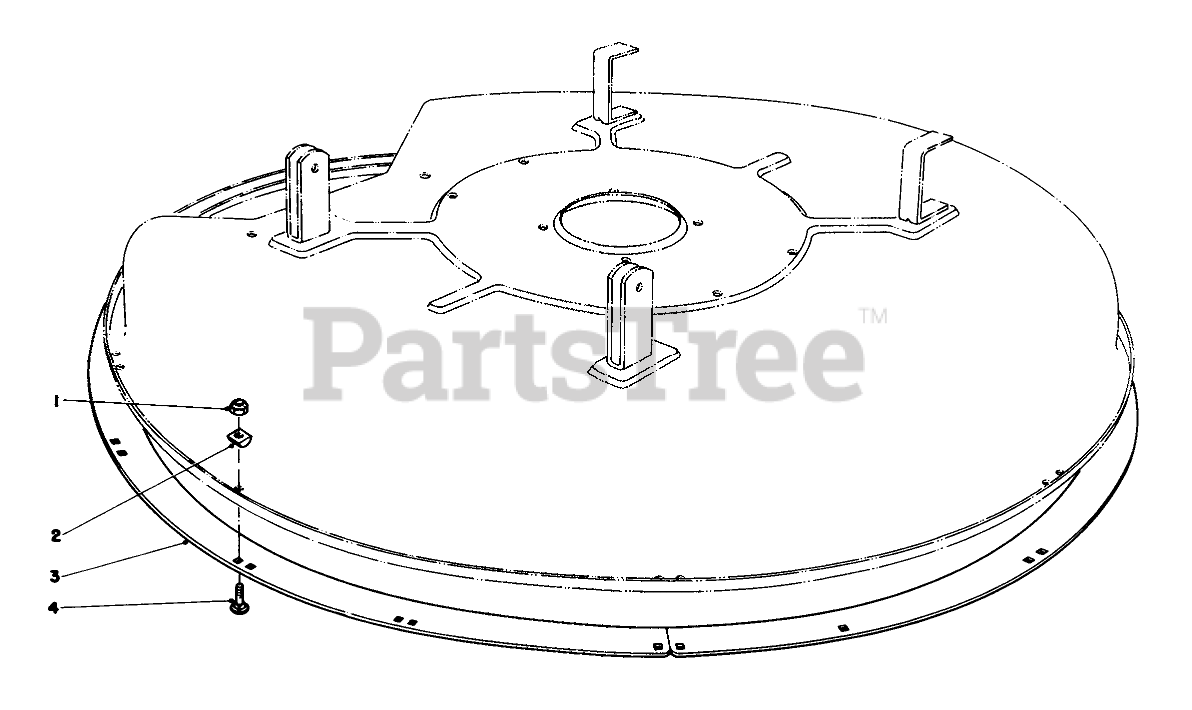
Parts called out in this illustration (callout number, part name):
1	NUT-LOCK, NI
2	DECK RING SPACER
3	DECK RING B
4	BOLT-CARR
